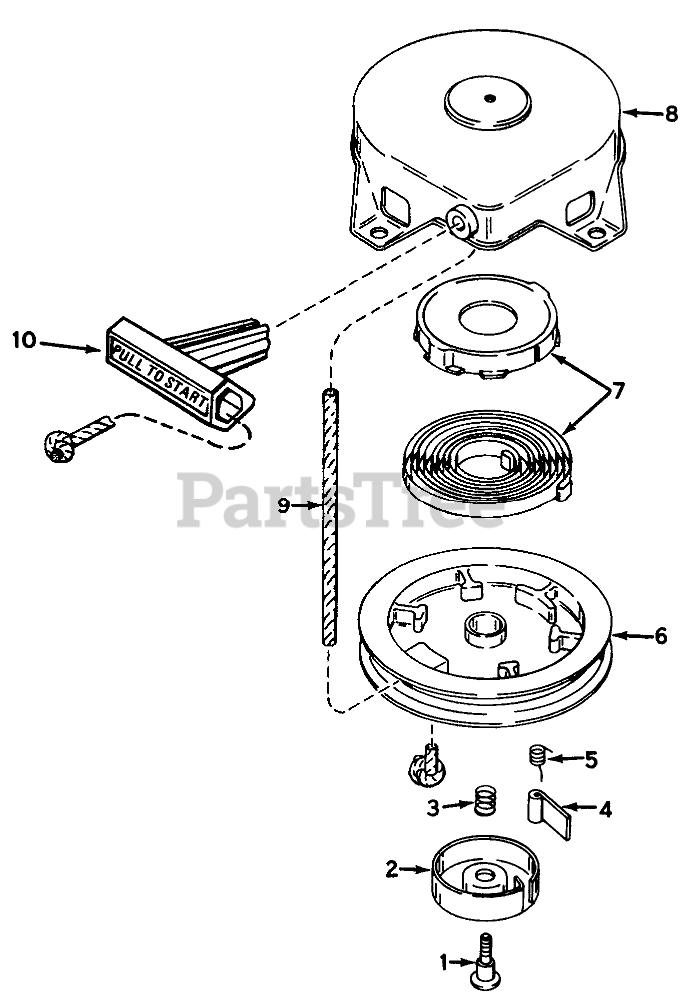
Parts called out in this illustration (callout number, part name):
2	Retainer
3	Spring-Brake
4	Dog-Starter
5	Spring-Dog
7	Spring & Keeper Assy
8	Housing-Starter
9	Rope-Starter (98 cut to length)
10	Handle-Starter
